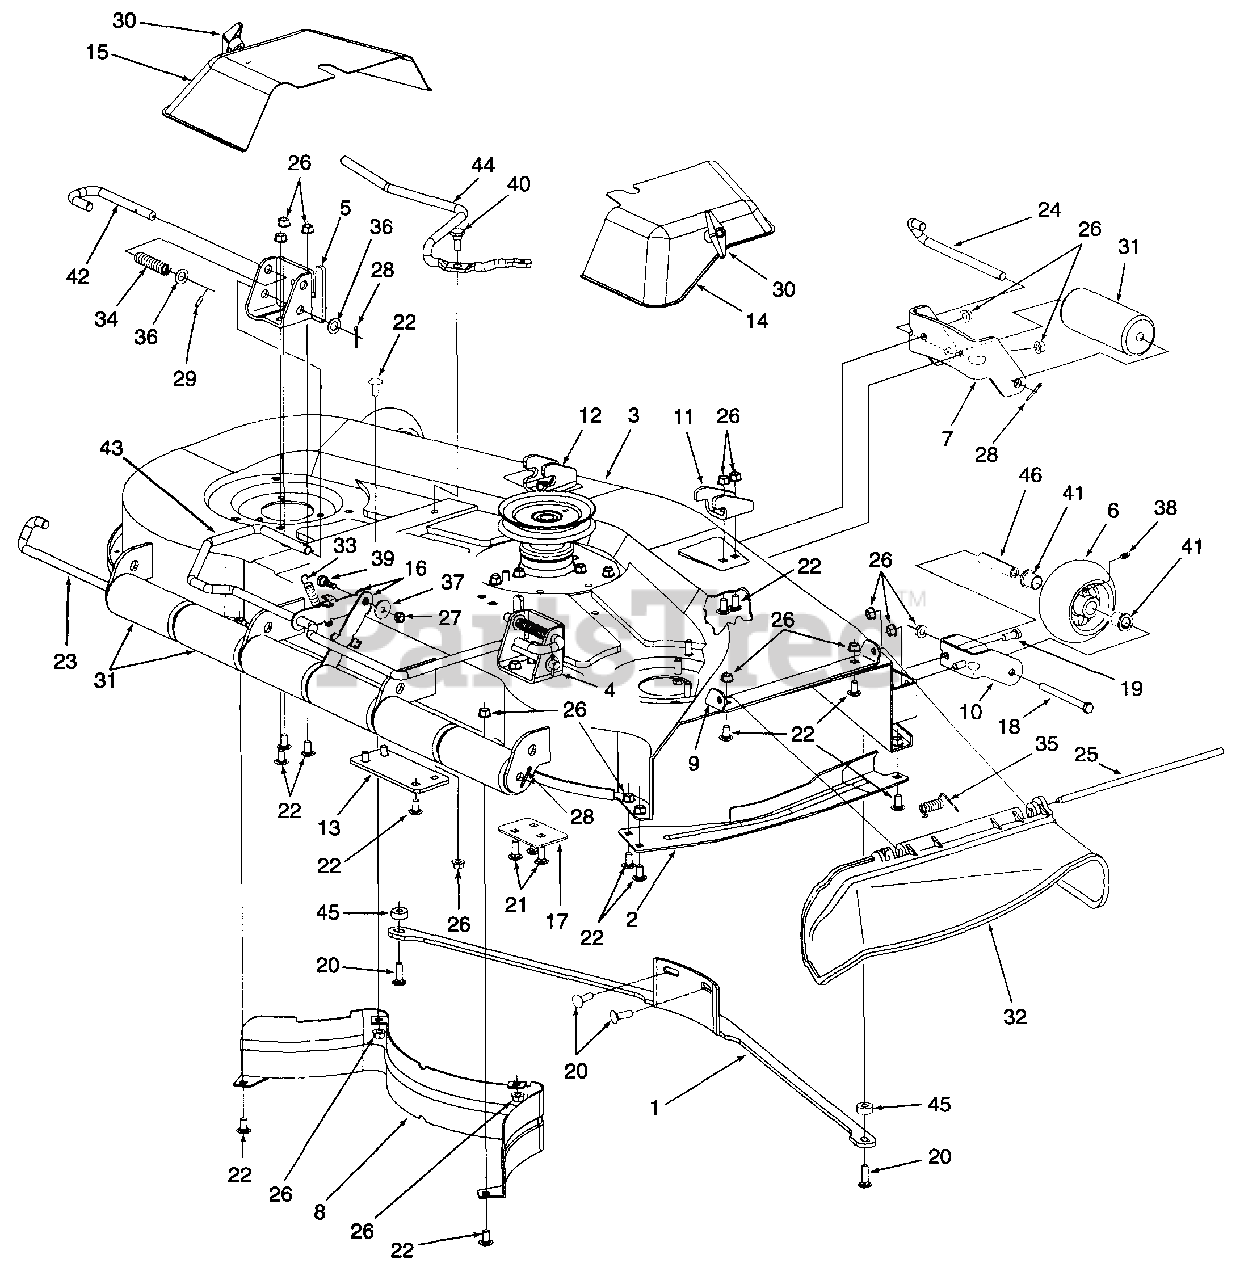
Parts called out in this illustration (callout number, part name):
19	Screw, Hex Cap, 3/8-16 x .88 GR5
20	Bolt, Carriage, 3/8-16 x 1.25 GR5
21	Bolt, Carriage, 3/8-16 x 1.0 GR5
22	Bolt, Carriage, 3/8-16 x .75 GR5
23	Pin, Roller
24	Pin, Roller, 1/2 x 7.31
25	Hinge Pin
26	Nut, Hex Flange Lock, 3/8-16
27	Nut, Hex Flange Lock, 5/16-18
28	Pin, Cotter 1/8 x 1.0
29	Pin, Spirol Spring, 3/16 x 3/4
30	Knob, Wingnut, 5/16-18
31	Roller, Front & Rear
32	Deflector, Plastic Chute
33	Spring, Extension
34	Spring, Compression
35	Spring, Torsion
36	Washer, Flat, .536 x .93 x .05
37	Washer, Flat, .344 x 1.125 x .12
38	Grease Fitting
39	Bolt, Shoulder, .437 x .268:5/16-18
40	Bolt, Shoulder, .50 x .267:3/8-16
41	Bearing, Flange
42	Pin, Mower Support
43	Rod, Deck Support
44	Rod, Idler Spring Mtg
45	Spacer, .406 x 1.0 x .38
46	Spacer, Wheel
